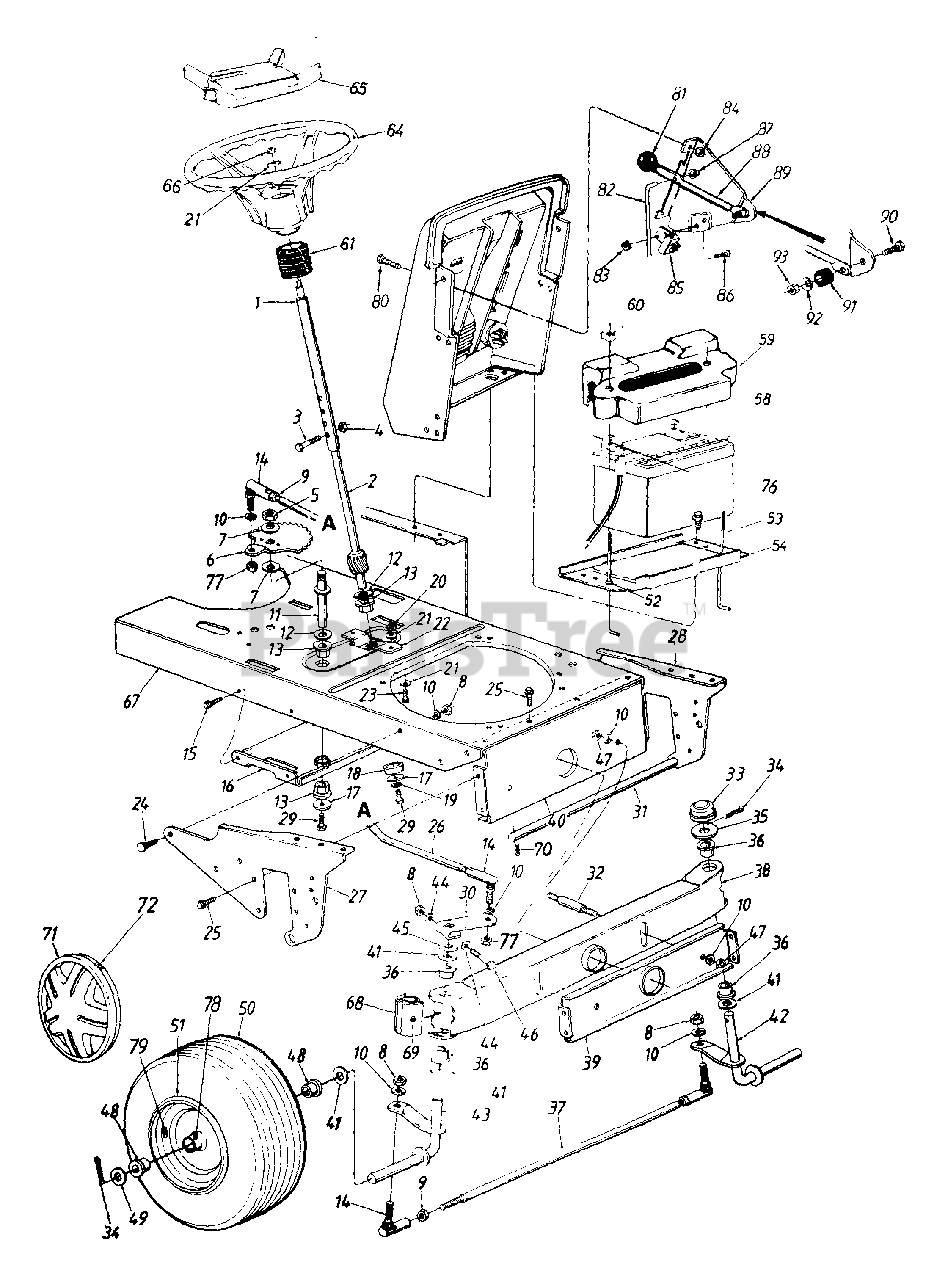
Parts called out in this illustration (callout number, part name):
1	Steering Column Ass'y.
2	Lower Steering Shaft
3	Hex Bolt 1/4-20 x 1.31" Lg.
4	Hex L-Nut 1/4-20 Thd.
5	Hex Nut 5/8-18 Thd.
6	Steering Gear Segment
7	Bell-Wash. 5/8" I.D. x 1.25" O.D.
8	Hex Nut 3/8-24 Thd.
9	Hex Jam Nut 3/8-24 Thd.
10	L-Wash. 3/8" I.D.
11	Steering Gear Segment Shaft
12	Fl-Wash. .64" I.D. x 1.24" O.D.
13	Hex Flange Brg..63" I.D.
14	Ball Joint Ass'y.
15	Hex Wash. Hd. TT-Tap Scr. 1/4-20 x .5" Lg.
16	Deck Idler Support Brkt.
17	Fl-Wash. .33" I.D. x 1.25" O.D.
18	Spacer .985" I.D. x 1.25" O.D.
19	L-Wash. 5/16" I.D.
20	Hex Nut 5/16-24 Thd.
21	Bell-Wash. .345" I.D. x .88" O.D.
24	Ribbed Neck Bolt 3/8-24 x .8" Lg.
25	Hex Wash. TT-Tap Scr. 5/16-18 x .62" Lg.
26	Steering Drag Link
27	Pivot Bar Side Plate - R.H.
28	Pivot Bar Side Plate - L.H.
29	Hex Bolt 5/16-18 x .62" Lg.
30	Steering Arm
31	Deck Connecting Rod
32	Pivot Bar Shld. Bolt 3/8-16 x 5/8" Lg.
33	Cap
34	Cotter Pin 5/32" Dia.
35	Flat Washer
36	Flange Brg. .757" I.D.
37	Tie Rod 20.25" Lg.
38	Pivot Bar Assy.
41	Fl-Wash. .76" I.D. x 1.49" O.D.
42	Front Axle Ass'y.- L.H.
43	Front Axle Ass'y.- R.H.
44	Bowed Washer
45	Spacer 755" I.D. x 1.25" O.D.
46	Hex Bolt 3/8-24 x 2.25" Lg.
47	Hex Nut 3/8-16 Thd.
48	Flange Brg. 75" I.D.
49	Fl-Wash..71" I.D. x 1.5" O.D.
51	Rim Only
52	Push Nut
53	Battery Hold Down Rod
54	Battery Plate
58	Battery (275 Cold Crank Amps)
59	Battery Cover
60	Wing Nut Plastic 1/4-20 Thd.
61	Steering Bellow
64	Steering Wheel
65	Steering Wheel Insert
66	Hex L-Nut 5/16-24 Thd
69	Grease Fitting
70	Internal Cotter Pin
71	Hub Cap
72	Spring Clip
76	Hex AB-Tap Scr 1/4 x 62" Lg.
77	Hex Jam L-Nut 3/8-24 Thd.
78	Grease Fitting
79	Air Valve
80	Truss Mach. Scr. 1/4-20 x .5" Lg.
81	Ball Knob
82	Deck Control Knob
83	Hex Sems Nut #10-24 Thd.
84	Hex Sems Nut 1/4-20 Thd.
85	Safety Switch
86	Truss Mach. Scr, #10-24 x .5"
87	Push Nut
88	Blade Clutch Lever
89	Deck Clutch Control Brkt.
90	Hex Bolt 1/4-20 x 1.25" Lg
91	Rubber Washer
92	Fl-Wash. .281" I.D. x .73"
93	Hex L-Nut 1/4-20 Thd.
